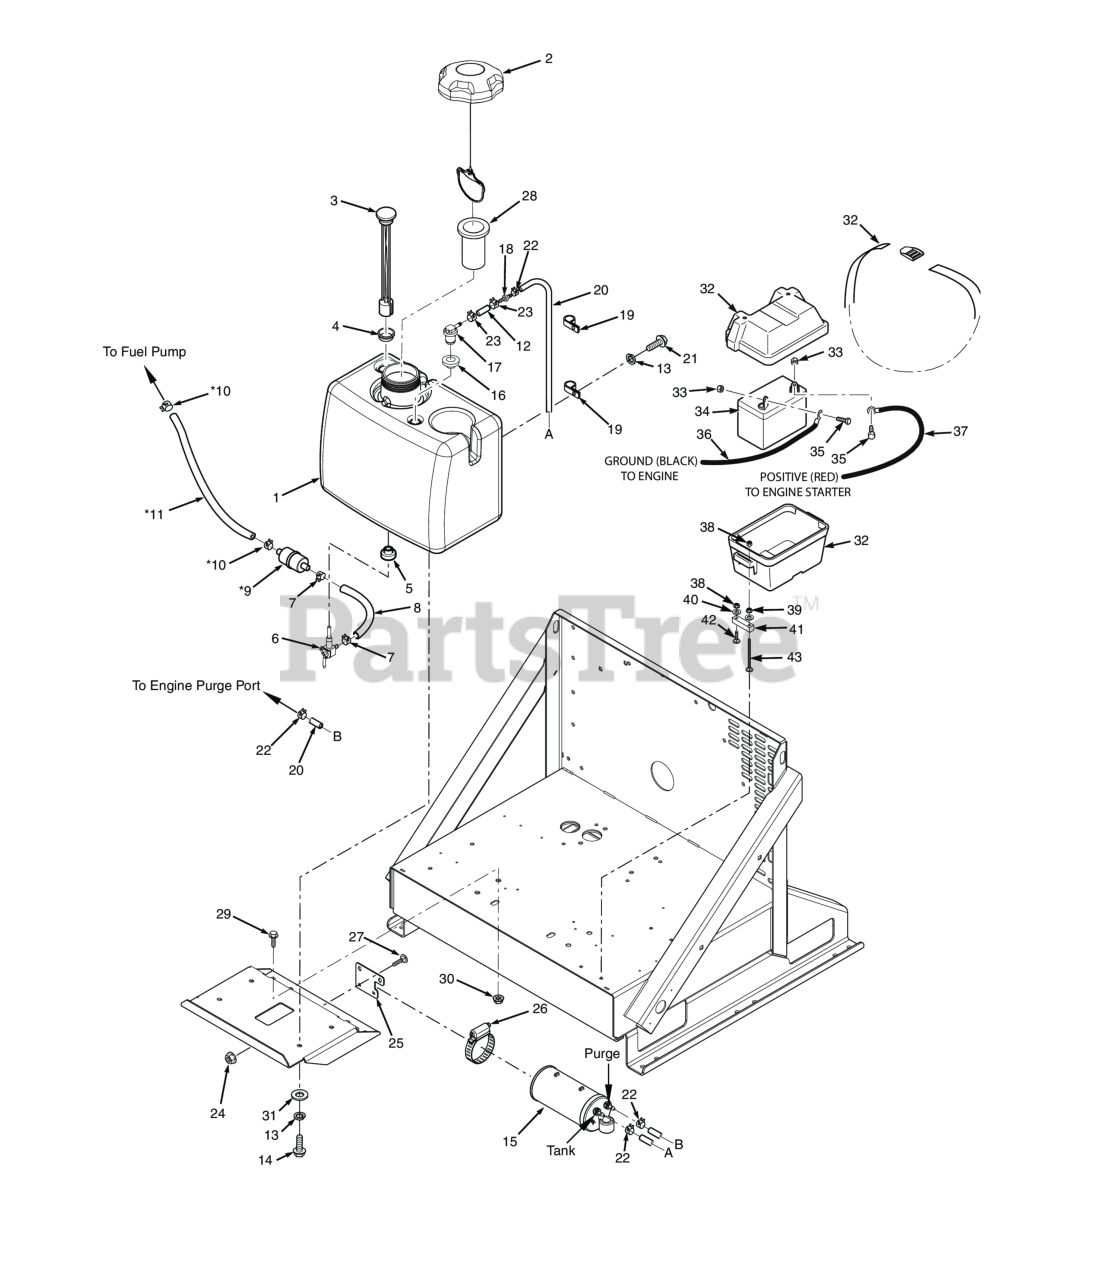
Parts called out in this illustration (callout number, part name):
1	Fuel Tank, TL20W
2	Fuel Cap w/ Tether (E.P.A.)
3	Fuel Gauge Assembly
4	Grommet, Fuel Gauge
5	Bushing, 0.56" Dia. Viton
6	Valve, Fuel Shut Off w/Screen
7	Clamp, Fuel Hose 1/4" Hose I.D.
8	Fuel Hose, 1/4" I.D. Non-Perm (791DFI Fuel Return) - Order by Inch
9	Fuel Filter (contact engine manufacturer)
10	Clamp (contact engine manufacturer)
11	Fuel Hose (contact engine manufacturer)
12	Hose, 1/4" Vapor Recovery (order by inch)
13	Lockwasher, 5/16 (.317 x .586 x .078) Helical Spring
14	BOLT, SERRATED FLANGE HEX HEAD 5/16-18 X 3/4"
15	Carbon Canister - SVR-36A / SVR-48V
16	Grommet, Viton,
17	Remote Vent, No Valve
18	Mender, 1/4 x 3/16 w/0.02 Hole
19	Clamp, Cable - .375 Dia.
20	Hose, Vapor Recovery 3/16" (order by inch)
21	BOLT, SERRATED FLANGE HEX HEAD 5/16-18 X 3/4"
22	Clamp, Vapor Recovery Hose 3/16"
23	CLAMP, FUEL HOSE(KAWASAKI ONLY)
24	Nut, Serrated Flange 5/16-18 (Right Front Engine Mounting, Briggs and Kohler Only)
25	Bracket, Cannister Mount
26	Clamp, 3-1/2" Max. Dia.
27	Bolt, Carriage 5/16-18x1" (large frame units only)
28	Tube, Fuel Tank Insert - 4"
29	Bolt, Hex Head 1/2-13 x 1-1/4"
30	Nut, Hex Serrated Flange 1/2-13
31	Flatwasher, 5/16-.375 x .875 x .083 (35BV & 37BV-EFI)
32	Battery Box w/Strap
33	Nut, 1/4 - 20 Hex
34	Battery (not available through Scag Power Equipment)
35	BOLT, HEX HEAD, 1/4-20 X 5/8
36	Battery Cable, 27" Black (35BV & 37BV-EFI) - Briggs & Stratton
37	Battery Cable, Red 32" w/Conduit
38	HEX, NUT, ELASTIC STOP LOCK, 1/4-20
39	NUT, 1/4-20 SERRATED FLANGE HEX HEAD
40	Flatwasher, 1/4" (.312 x .750 x .065")
41	Spacer, Battery Bob (x6)
42	Bolt, Carriage, 1/4-20 x 1-1/4"
43	Bolt, Carriage 1/4-20 x 6"
